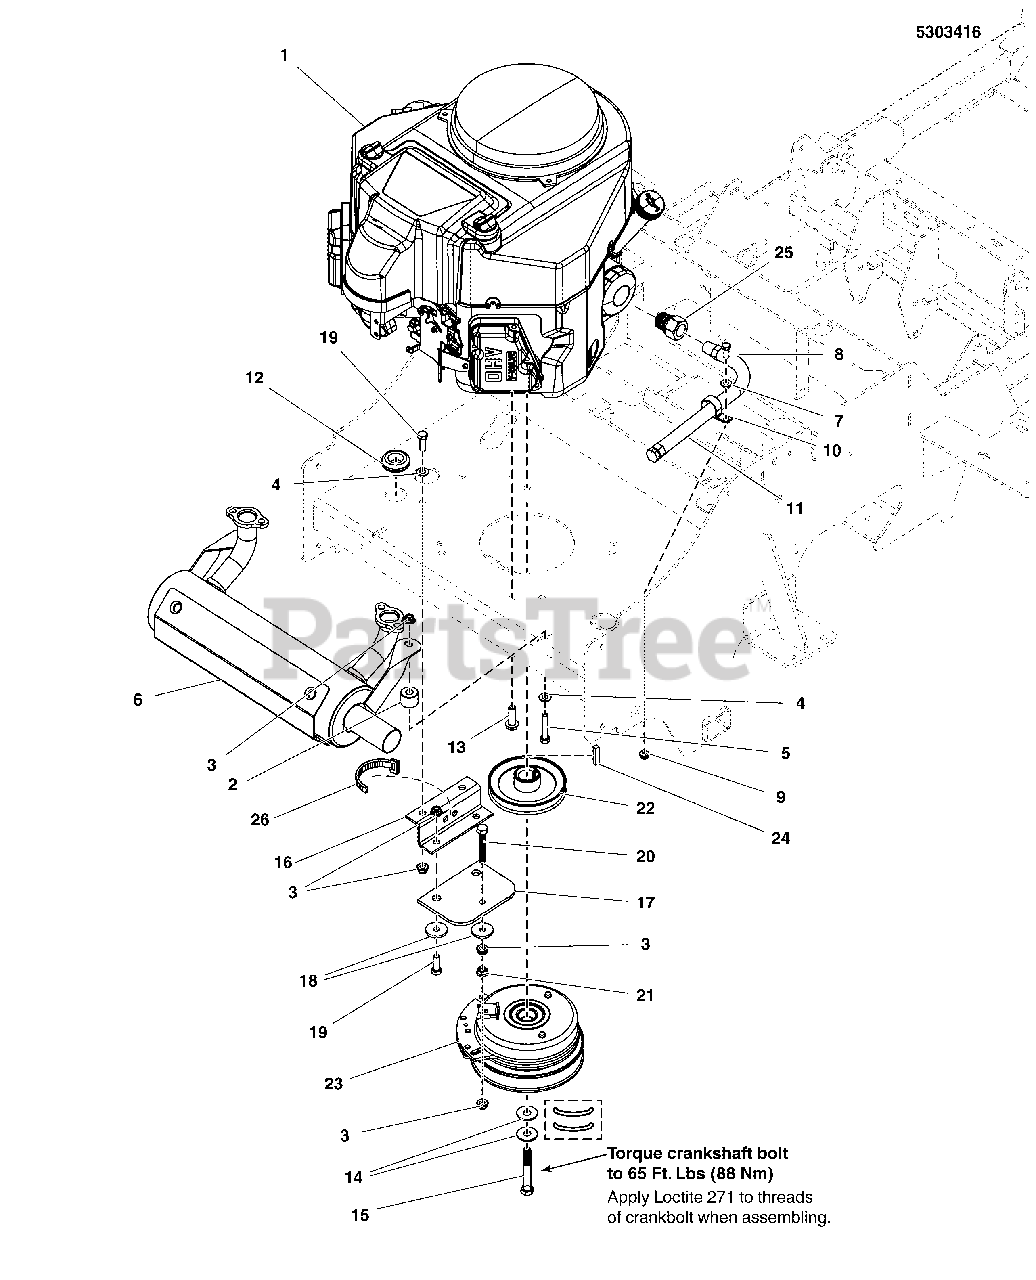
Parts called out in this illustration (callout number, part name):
1	ENGINE, 24HP KAWI, FR, 1" CRANK
2	SPACER, .39 X 1.00 X .80, CZ
3	NUT, 5/16-18 HEX NYLOCK FLANGE
4	WASHER, 5/16 SAE
5	BOLT, 5/16-18 X 1-3/4 GD5 YZ
6	MUFFLER, 26HP KAWI, FX730V, HORIZONTAL
7	WASHER, Flat, 1/4
8	BOLT, 1/4-20 X 3/4 GD5 YZ
9	NUT, Nylock Flanged, 1/4-20
10	CLAMP, VINYL INSULATED
11	HOSE, OIL DRAIN
12	GROMMET, 7/8
13	BOLT, 3/8-16 X 1-1/4, SF, PLT W/PATCH
14	BELLEVILLE WASHER 1.1875 X .442 X .089
15	BOLT, CRANKSHAFT, 7/16-20 X 3-1/4, GD8
16	ANCHOR, CLUTCH - BLK
17	CLUTCH ANCHOR PAD
18	WASHER, .34 X 1.25 X 10 GA
19	CAPSCREW, Hex Head, 5/16-18 x 1
20	BOLT, 5/16-18 X 2-1/4
21	NUT, Hex Serrated Flange, 5/16-18,
22	PULLEY, PUMP DRIVE, 4.857 OB X 1" BORE
23	CLUTCH, # 5219-34A, ELECTRIC, IS500Z
24	KEY, 1/4 SQ X 1
25	ADAPTER-OIL DRAIN
26	TIE,SELF-LOCKING, 6"
